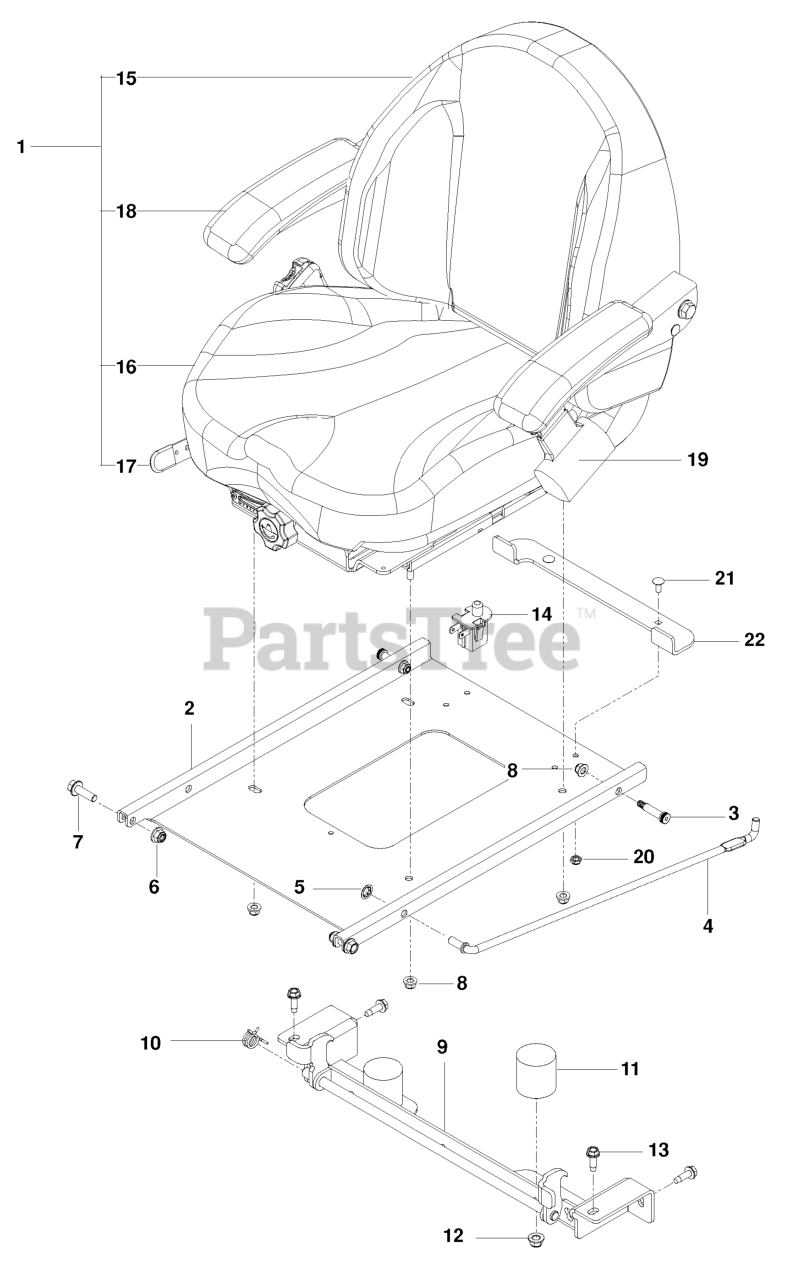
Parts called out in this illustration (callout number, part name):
1	Seat Assy
2	PAN, SEAT, BLACK
3	BOLT, SHOULDER 3/8 X 1.25
4	ROD, SEAT
5	NUT 3/8 PALNUT RTNG BLK PHOS
6	NUT 3/8-16 HEX FLG NYLOC ZD
7	HHFS 3/8-16 X 1.25 GD 5
8	5/16-18 NYLOC FLANGE NUT
9	LATCH.SEAT.BLACK
10	SPRING, TORSION
11	BUMPER, RUBBER
12	NUT 3/8-16 HEX FLG NYLOC ZD
13	RP BLT 5/16-18 X 1 THRD FORM D
14	SEAT SWITCH
15	COVER, BACK
16	COVER KIT, CUSHION
18	ARMREST, LT
19	Seat Belt
20	JAM NUT 1/4C (2 2 PW01)
21	RHSSNB, 1/4-20X5/8
22	STOP, SEAT, BLK
